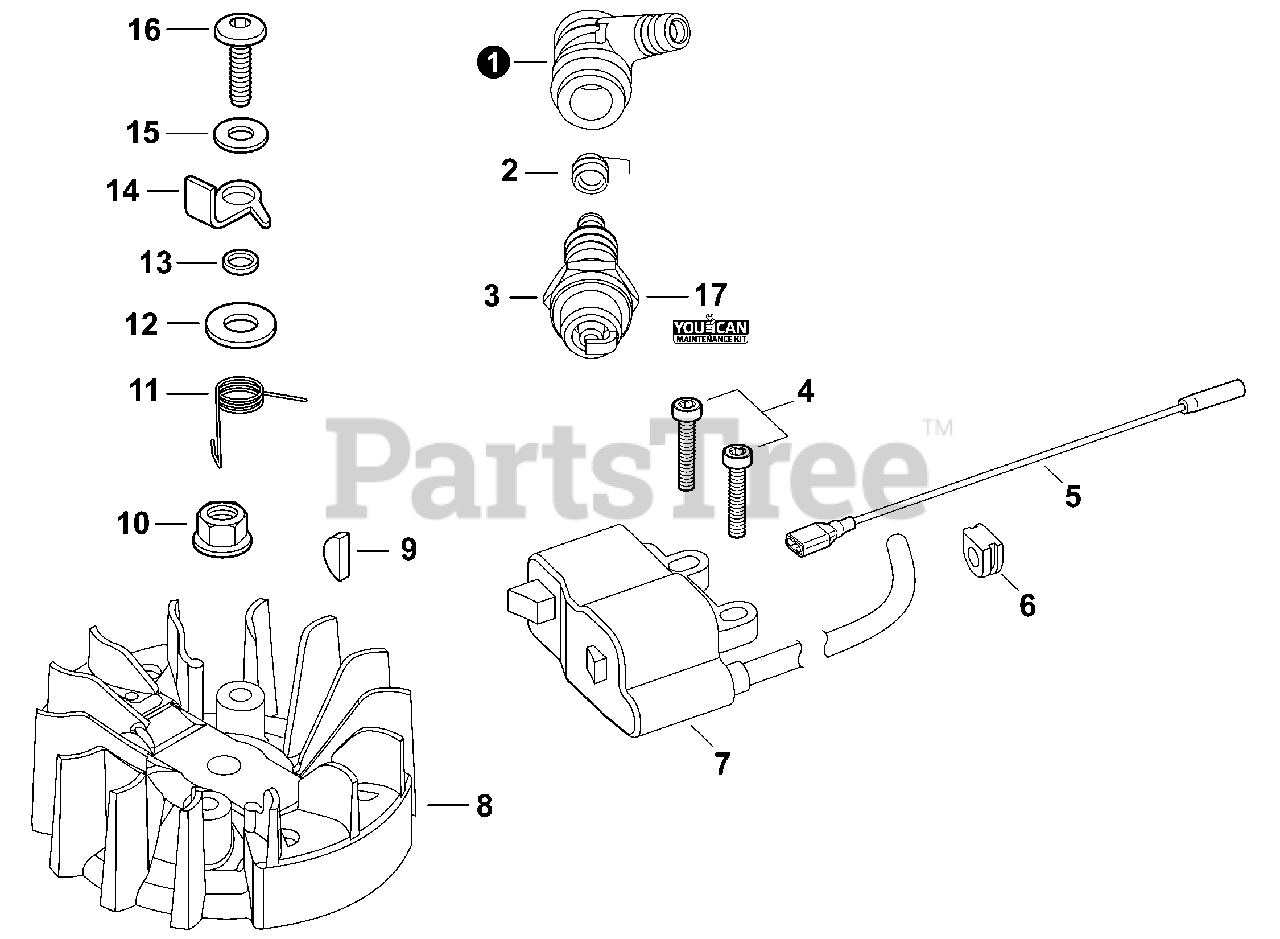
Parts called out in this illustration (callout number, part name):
1	CAP, SPARK PLUG
2	TERMINAL, SPARK PLUG
3	SPARK PLUG - BPM8Y
4	SPARK PLUG - BPMR8Y
5	BOLT, TORX 4×16
6	LEAD L= 85 mm
7	GROMMET
8	COIL, IGNITION
9	FLYWHEEL
10	KEY, WOODRUFF
11	NUT, FLANGE M6
12	SPRING, TORSION
13	WASHER 5.5×16×0.8
16	WASHER 5.5×12×0.8
17	BOLT 5×14
18	PLUG & FILTER KIT - YOU CAN
